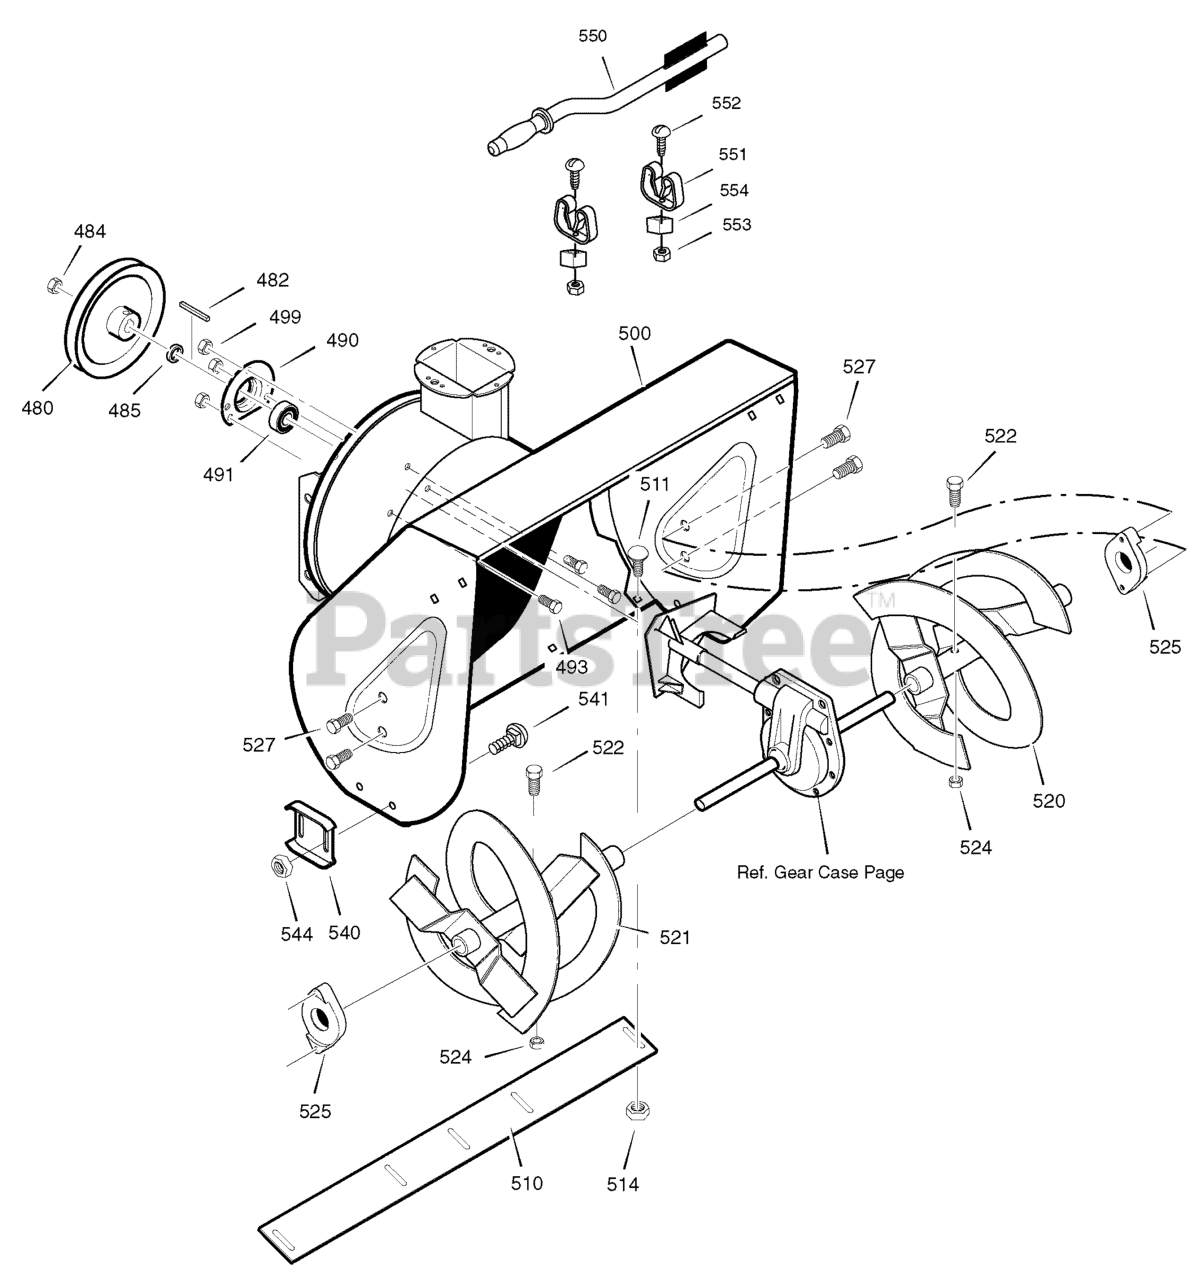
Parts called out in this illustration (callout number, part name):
480	PULLEY, 4L 8.40 OD
482	KEY, SQUARE 3/16 X 3/4
484	NUT, 1/2--20
485	SPACER, FRICTION PULLEY
490	RETAINER, BALL BRNG
491	BEARING, BALL
493	BOLT, HEX 5/16--18X .50
499	NUT, 5/16--18 HEXWDFLLK
500	HOUSING, ASSY
510	BLADE, SCRAPER
511	BOLT, 5/16--18X.62
514	NUT, 5/16--18
520	AUGER, ASSY, LH
521	AUGER, ASSY, RH
522	SCREW, 5/16-18
524	NUT, 5/16--18
525	BEARING, FLANGE
527	SCREW, 5/16-18 x 0.75
540	SKID, HEIGHT ADJUST
541	BOLT, 5/16--18 X .50
544	NUT, 5/16--18
550	BRUSH, CLEANOUT
551	CLIP, RETAINER
